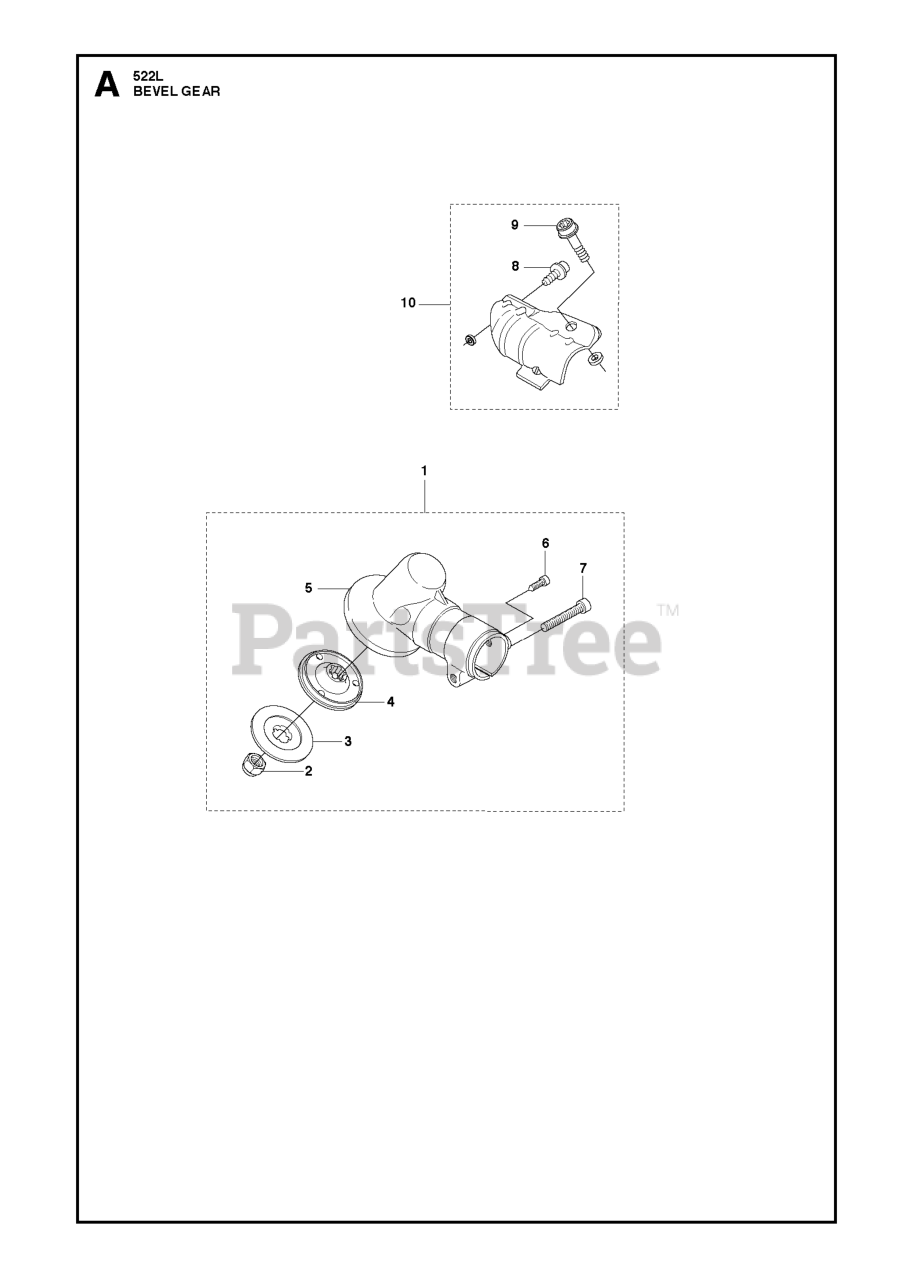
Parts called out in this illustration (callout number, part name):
1	GEAR HEAD
2	GEARHEAD NUT - BRUSHCUTTER
3	SUPPORT FLANGE
4	DRIVE DISC
10	ASSY CLAMP 523L
